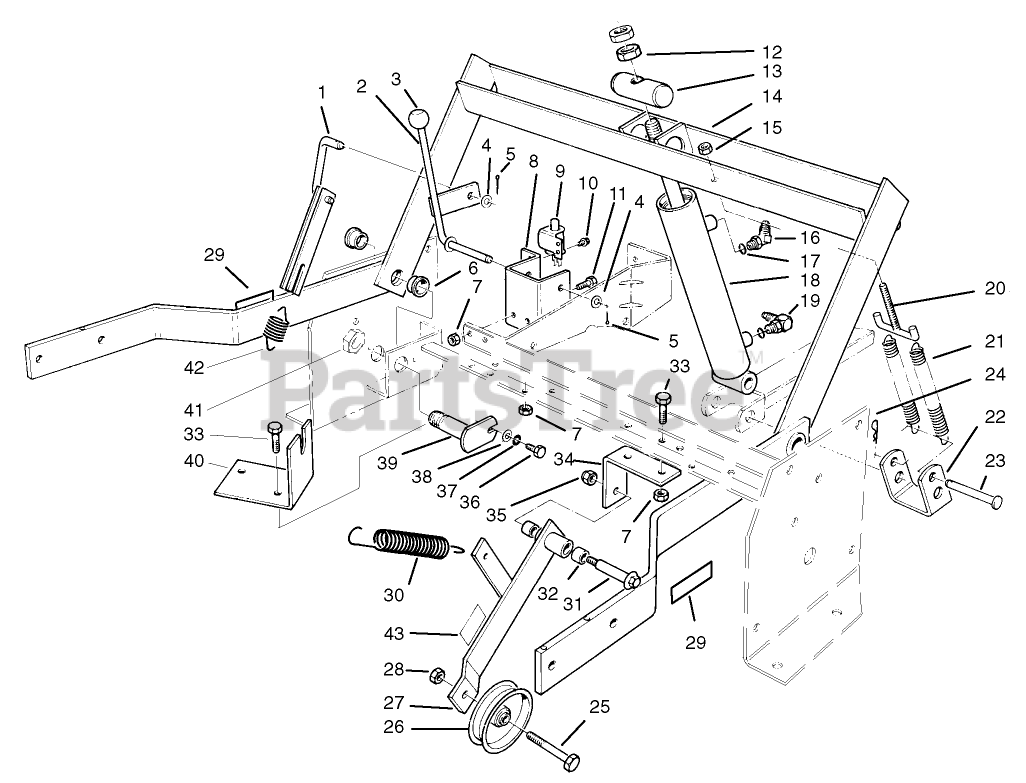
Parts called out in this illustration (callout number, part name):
1	Link-Parking Brake
2	Brake Lever
4	WASHER-FLAT
5	PIN-COTTER
6	BEARING-FLANGE
7	NUT-LOCK, NI
8	Bracket-Parking Brake
9	SWITCH-BRAKE, PARKING
10	SCREW-TAPTITE
11	SCREW-HH
12	NUT-JAM
13	CYL.PIVOT PIN
14	Frame-Lift (Incl. Ref. #6)
15	NUT-HEX, SIDE DEFORM
16	FITTING-45 DEG
17	O-RING
18	CYLINDER - LIFT
19	FITTING-ELBOW, 90
20	T-HOOK W A
21	SPRING_EXTENSION
22	SPRING BRACKET
23	PIN-CLEVIS
24	PIN-HAIR
25	SCREW-HH
26	PULLEY-IDLER
27	Lever-Idler (Incl. Ref. #43)
28	NUT-LOCK, NI
29	WARNING DECAL
30	IDLER EXT SPRING
31	BOLT-WHEEL
32	BUSHING
33	SCREW-HH
34	JACKSHFT IDLR BRKT
35	NUT-LOCK
36	SCREW-HH
37	WASHER-LOCK
38	WASHER-FLAT
39	Pin-Pivat
40	TRACT CABLE BRKT
41	NUT-LOCK, NI
42	PARK BRAKE SPRING
43	DECAL-WARNING
